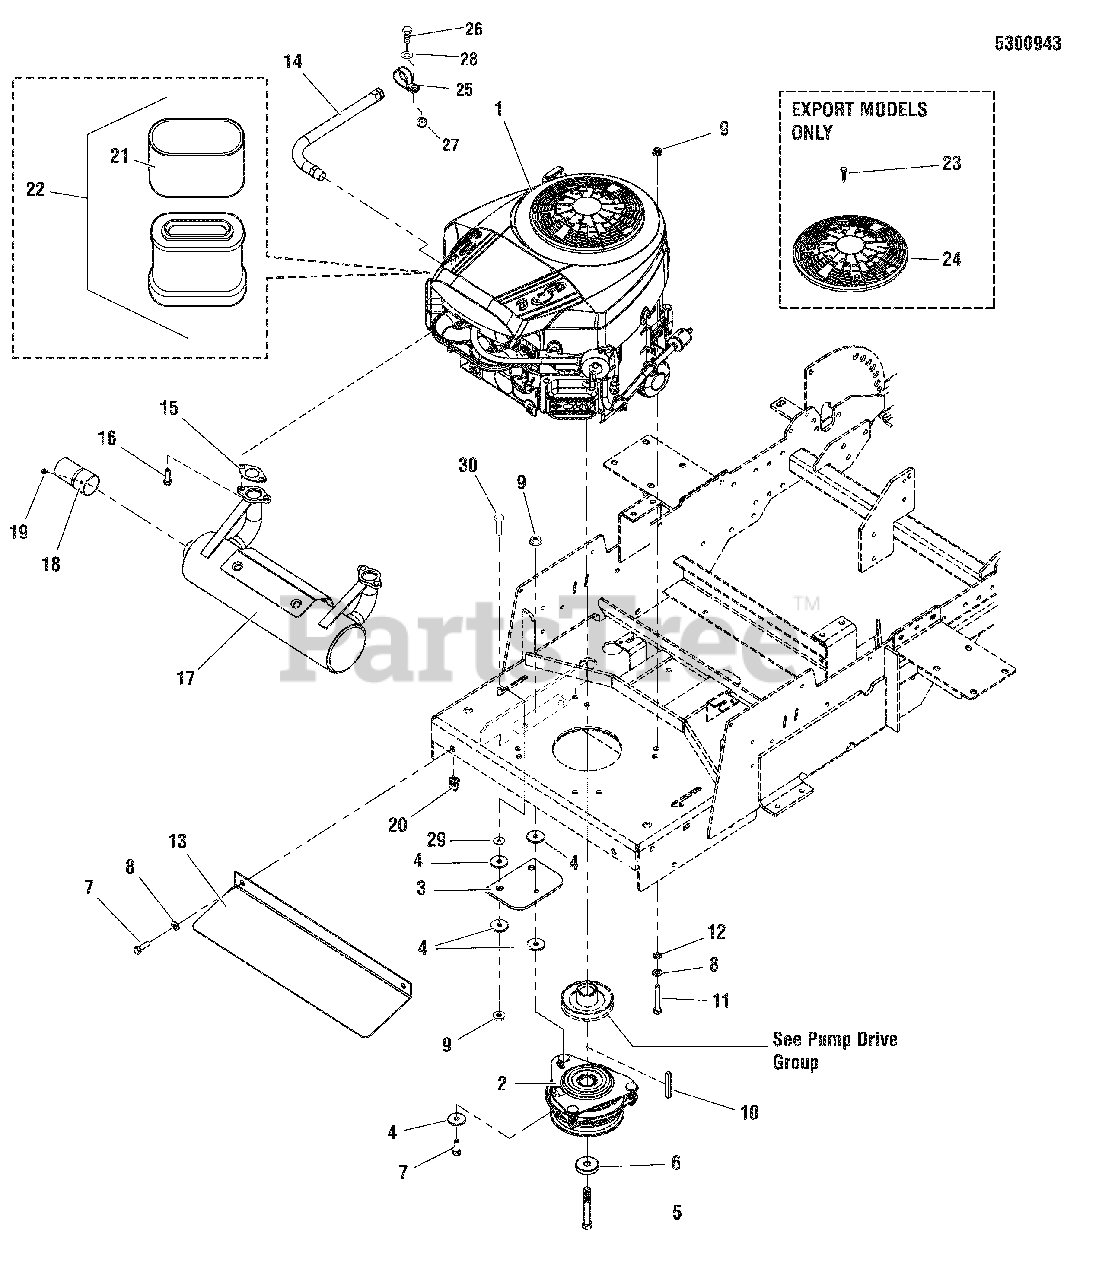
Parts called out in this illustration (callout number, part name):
1	* ENGINE, Briggs & Stratton, ELS
2	CLUTCH,#51110100,ELECTRIC, 1" SHAFT
3	CLUTCH ANCHOR PAD
4	WASHER, .34 X 1.25 X 10 GA
5	CAPSCREW, CRANKSHAFT, 7/16-20 x 3-1/4"YZ
6	SPACER, .45 X 1.62 X .37
7	BOLT, 5/16-18 X 1 GD5 YZ
8	WASHER, 5/16 SAE
9	NUT, 5/16-18 HEX NYLOCK FLANGE
10	KEY, 1/4" SQ. X 2 1/4
11	BOLT, 5/16-18 X 2-1/4" GD5 YZ
12	WASHER, 5/16" INT. TOOTH LOCK
13	PLATE, HEAT SHIELD - ORG
14	HOSE, OIL DRAIN
15	GASKET, EXHAUST
17	MUFFLER, B&S-ELS
18	EXTENSION, TAILPIPE, 3" - BLK
20	BODY CLIP, 5/16-18 X 1/2 DEEP
21	PRE CLEANER (SV)
22	AIR CLEANER W/ PRE CLEANER (SV)
23	SCREW, CROSS RECESSED THREAD
24	COVER, STATIC / LABEL ASSEMBLY
29	NUT, 5/16-18 HEX SERRATED FLANGE (LARGE)
30	BOLT, 5/16-18 X 1-1/4 GD5 YZ
